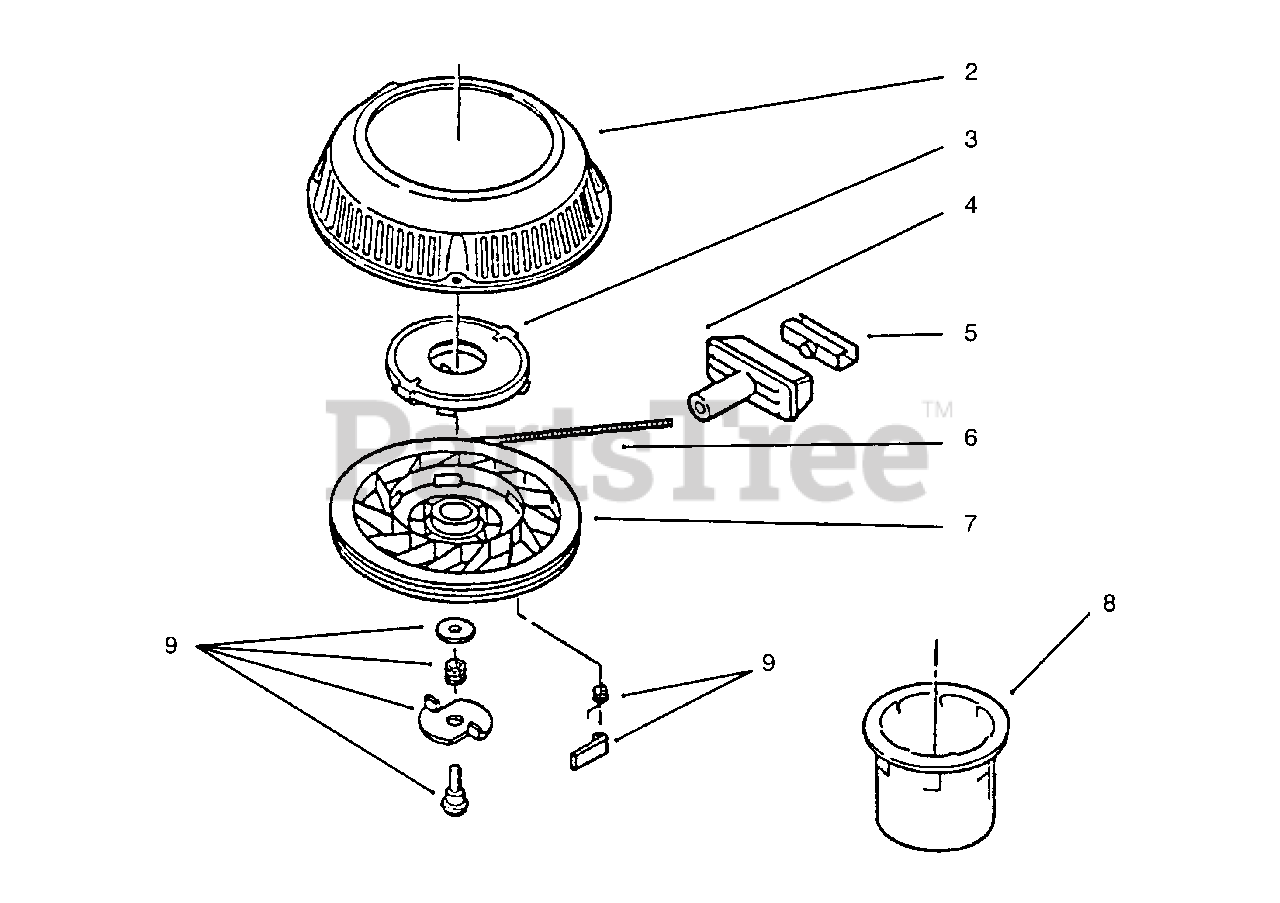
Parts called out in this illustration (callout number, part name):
2	Starter Housing & Shaft
3	Spring & Keeper
4	Handle-Starter
5	Clip-Rope
6	Rope
8	Hub-Starter
9	Kit-Dog
